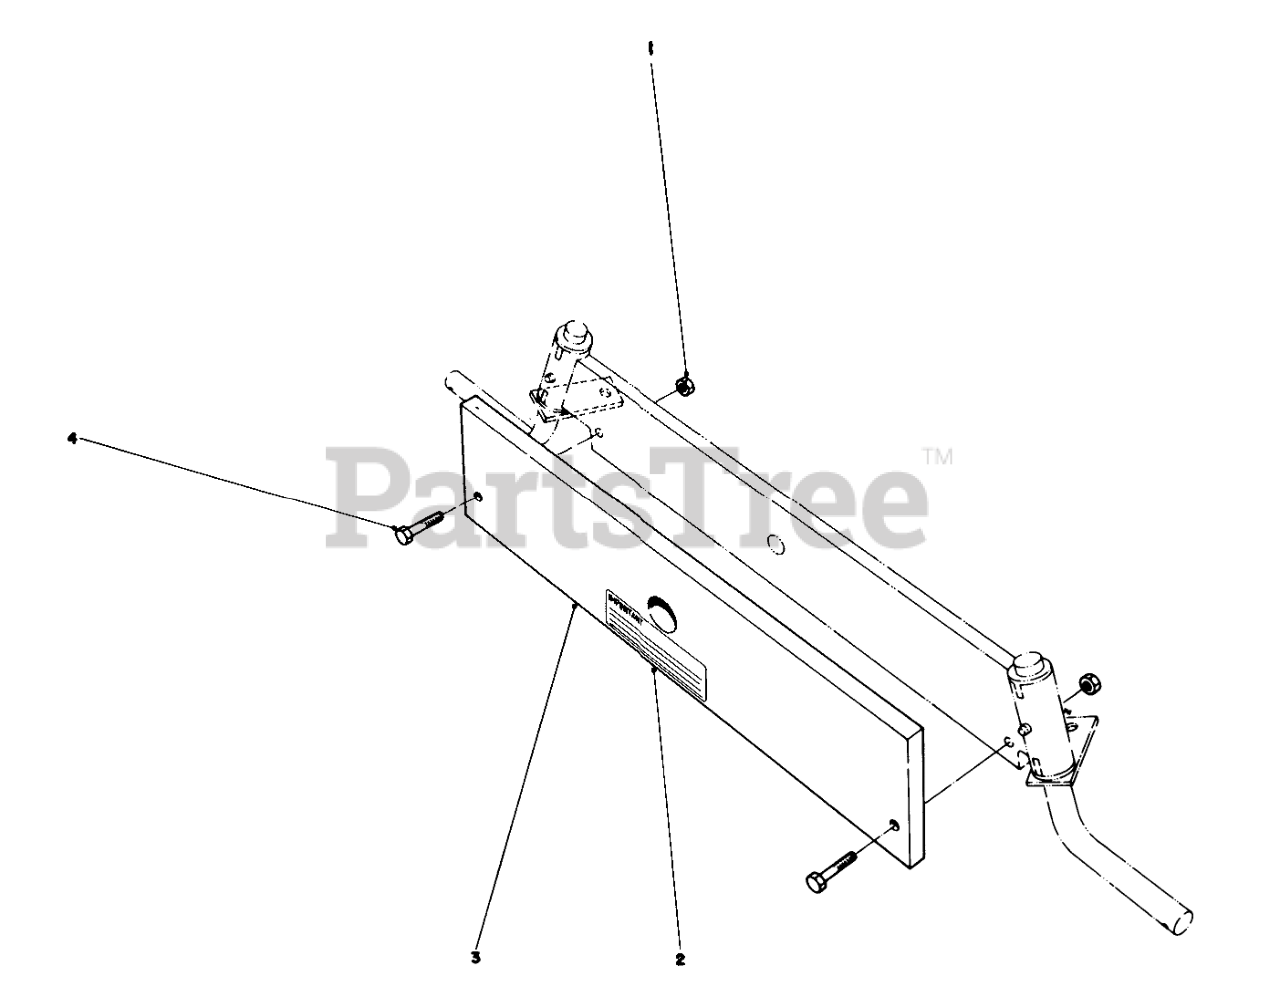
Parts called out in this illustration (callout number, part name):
1	NUT-LOCK, CONE
2	Decal Instructions
3	COUNTERWEIGHT B
4	SCREW-HH
